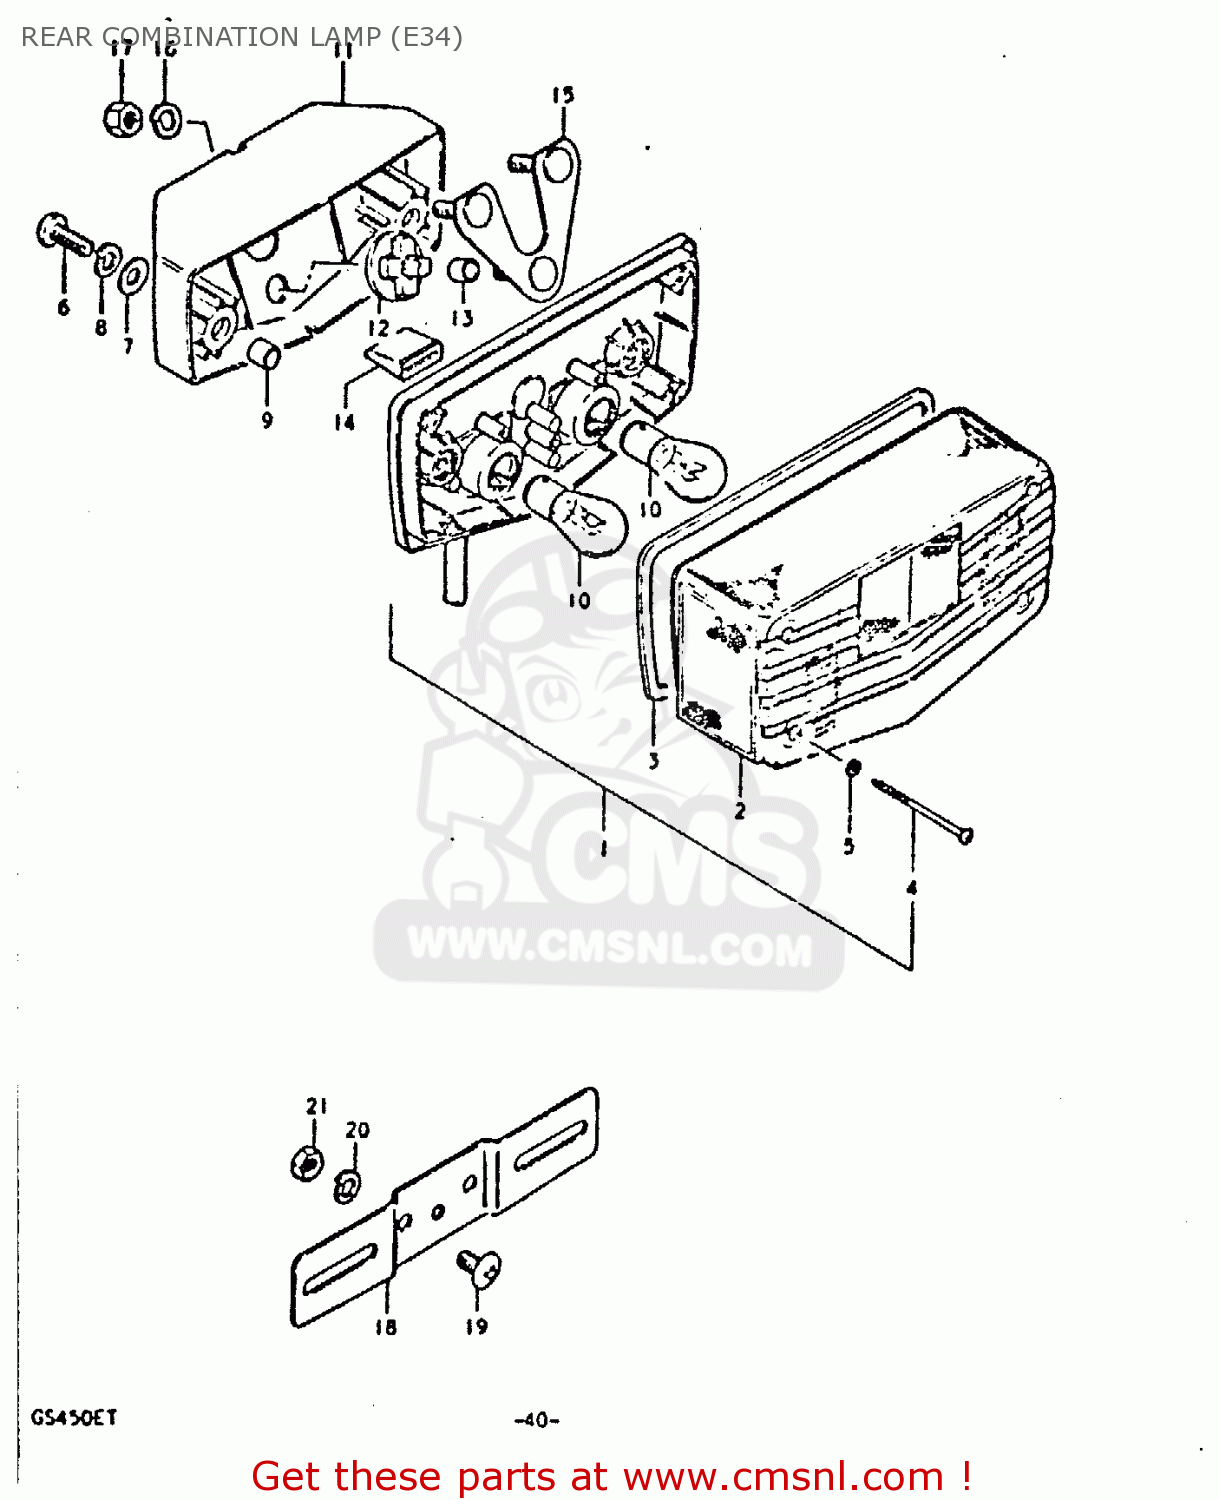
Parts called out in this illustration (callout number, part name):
1	LAMP UNIT, REAR COMBINATION
2	LENS
3	GASKET,REAR COMBINATION LAMP LENS (NAS)
4	SCREW
5	GASKET (NAS)
6	SCREW
7	WASHER
8	LOCK WASHER
9	SPACER,REAR COMBINATION LAMP
10	BULB(EXECUTED LOCALLY 12V, 21/5W)
11	BRACKET UNIT,TAIL LAMP
12	CUSHION,REAR COMBINATION LAMP
13	SPACER,REAR COMBINATION LAMP
14	CUSHION,REAR COMBINATION LAMP
15	PLATE,REAR COMBINATION LAMP
16	LOCK WASHER
17	NUT
18	PLATE,RR LICENSE
19	SCREW
20	LOCK WASHER
21	NUT
